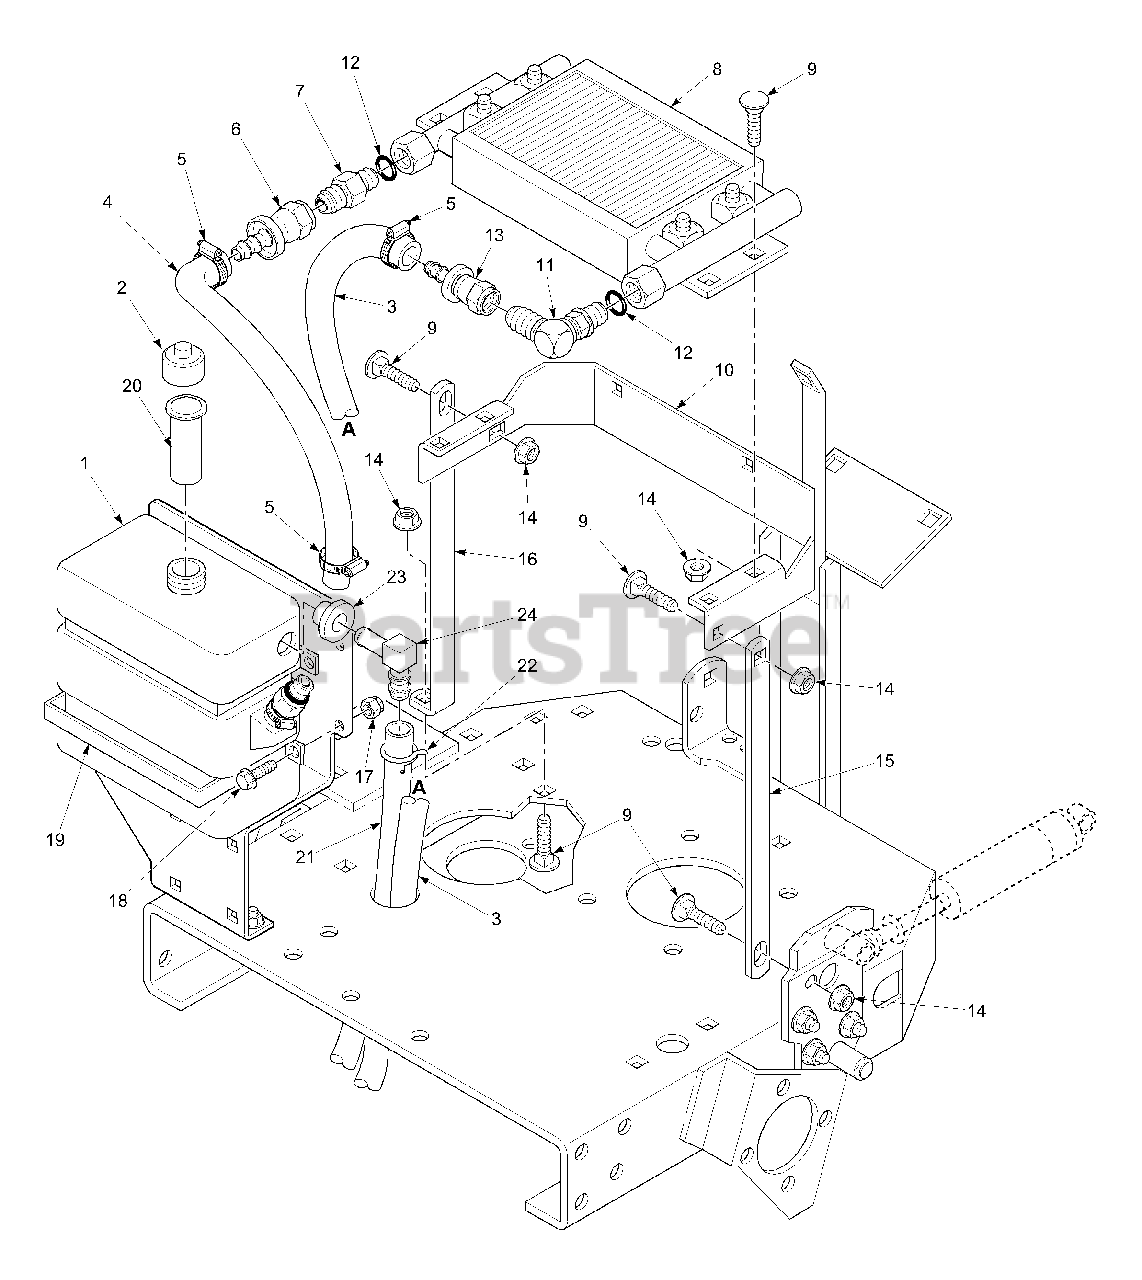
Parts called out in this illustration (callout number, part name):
1	Tank, Hydraulic
2	Cap, Hydraulic Tank
3	Hose, Pump to Oil Cooler
4	Hose, Oil Cooler to Tank
5	Clamp, Hose
6	Coupling, Flare Swivel
7	Tube, Union
8	Oil Cooler Assembly
9	Carriage Bolt, 5/16-18 x 3/4"
10	Bracket, Oil Cooler
11	Elbow, 90 Degrees
12	O-Ring
13	Coupling Flare Swivel
14	Serr. Fl. Hex Head Nut, 5/16-18
15	Brace, L.H. Cooler Support
16	Brace, R.H. Cooler Support
17	Elastic Stop Nut, 1/4-20
18	Serr. Fl. Hex Head CPSCR, 1/4-20 x 3/4"
19	Strap, Oil Tank
20	Filler Neck Insert
21	Hose, 1/4" Pushlock, Order by the inch
23	Bushing
24	90 Degree Elbow
